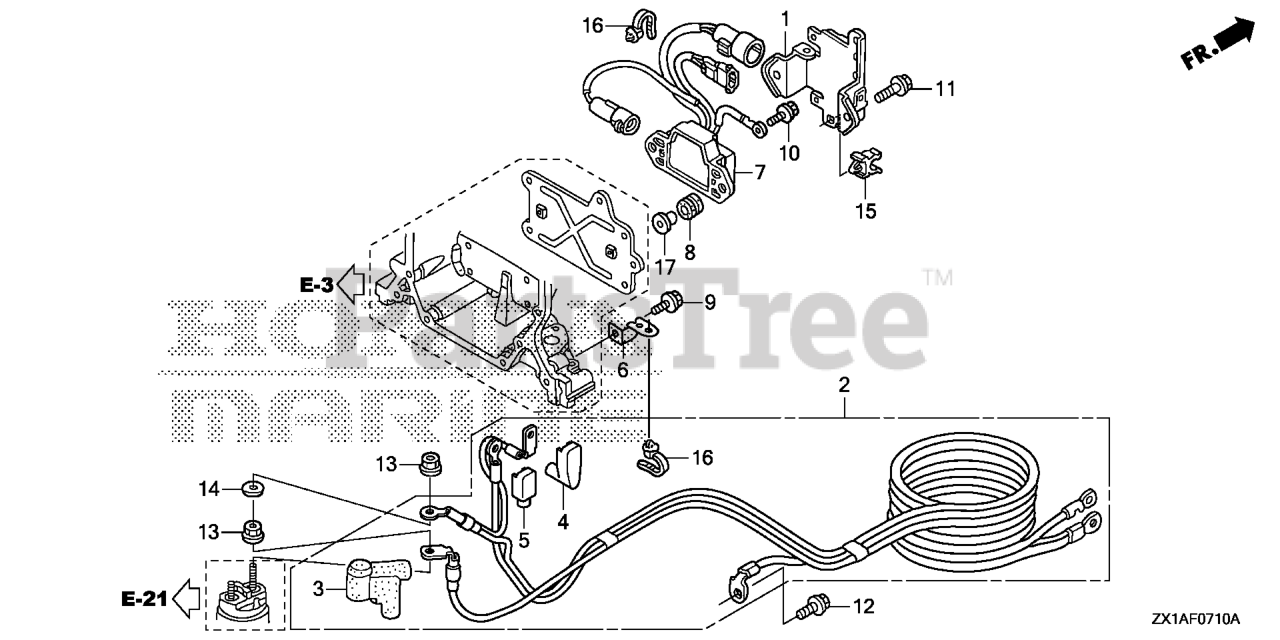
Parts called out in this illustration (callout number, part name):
1	BRACKET A, CONNECTOR
2	CABLE ASSY., STARTER
3	COVER, STARTER TERMINAL
4	COVER B, TERMINAL (L)
5	COVER B, TERMINAL
6	BRACKET B, CABLE
7	RELAY ASSY., POWER TILT
8	GROMMET, RELAY
9	BOLT, FLANGE (6X14) (CT200)
10	BOLT, FLANGE (6X12)
11	BOLT, FLANGE (6X22)
12	BOLT, FLANGE (8X18)
13	NUT-WASHER (8MM)
14	WASHER, PLAIN (8MM)
15	CLIP, FUEL TUBE (14) (NOT AVAILABLE)
16	CLIP, HARNESS BAND (145MM) (BLACK)
17	COLR, CDI UNIT CASE
17	COLLAR, MODULE IGNITION CONTROL CASE (CDI)
